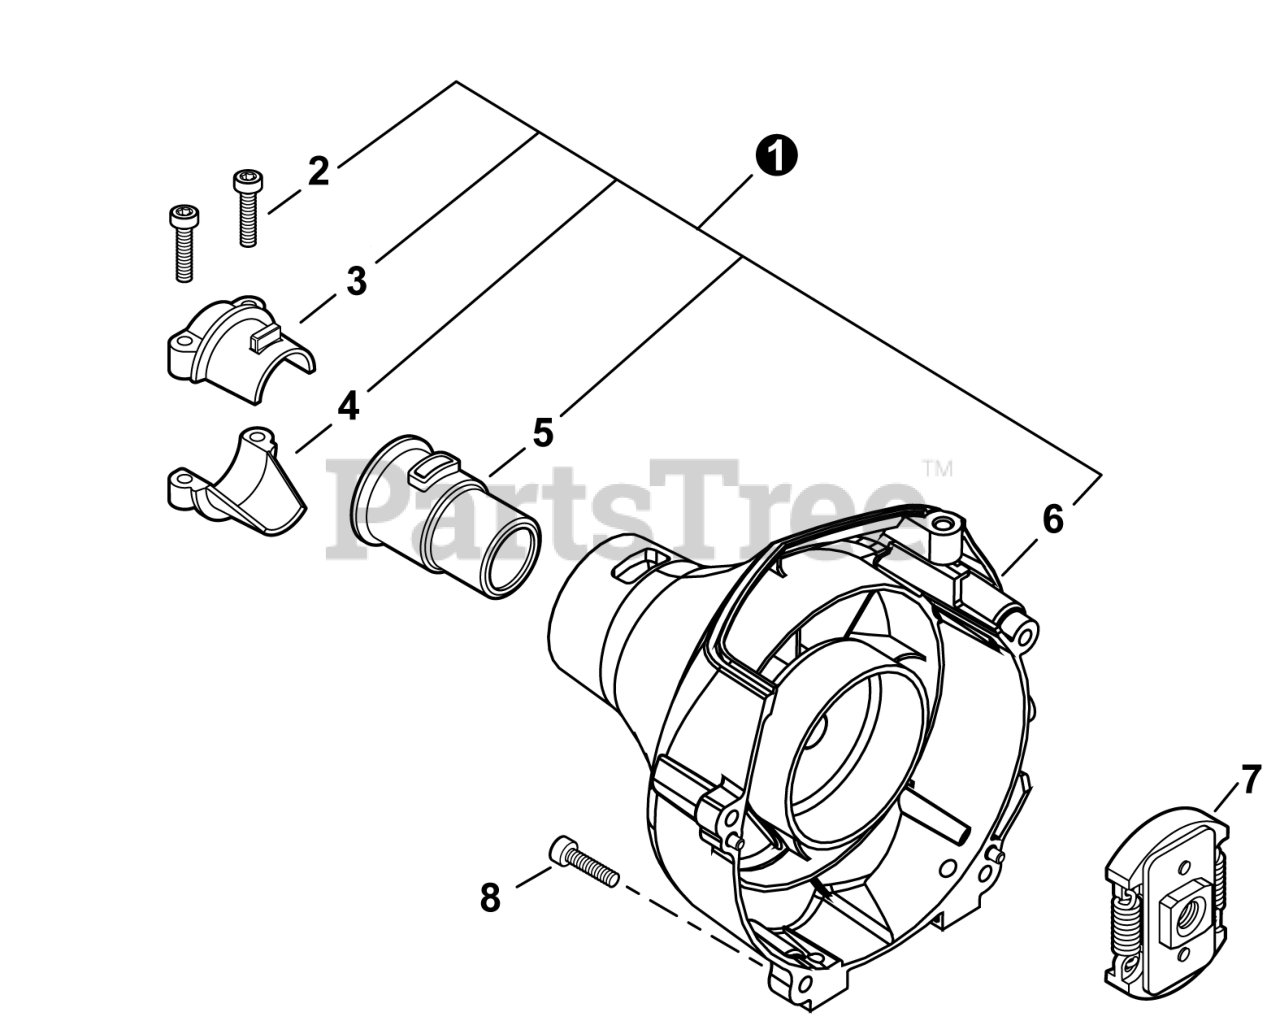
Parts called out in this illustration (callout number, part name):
1	COVER ASSY, FAN
2	BOLT, TORX 5x20
3	HOLDER, MAIN PIPE - UPPER
4	HOLDER, MAIN PIPE - LOWER
5	CUSHION, MAIN PIPE
6	COVER ASSY, FAN
7	CLUTCH ASSY
8	BOLT, TORX 4x16
